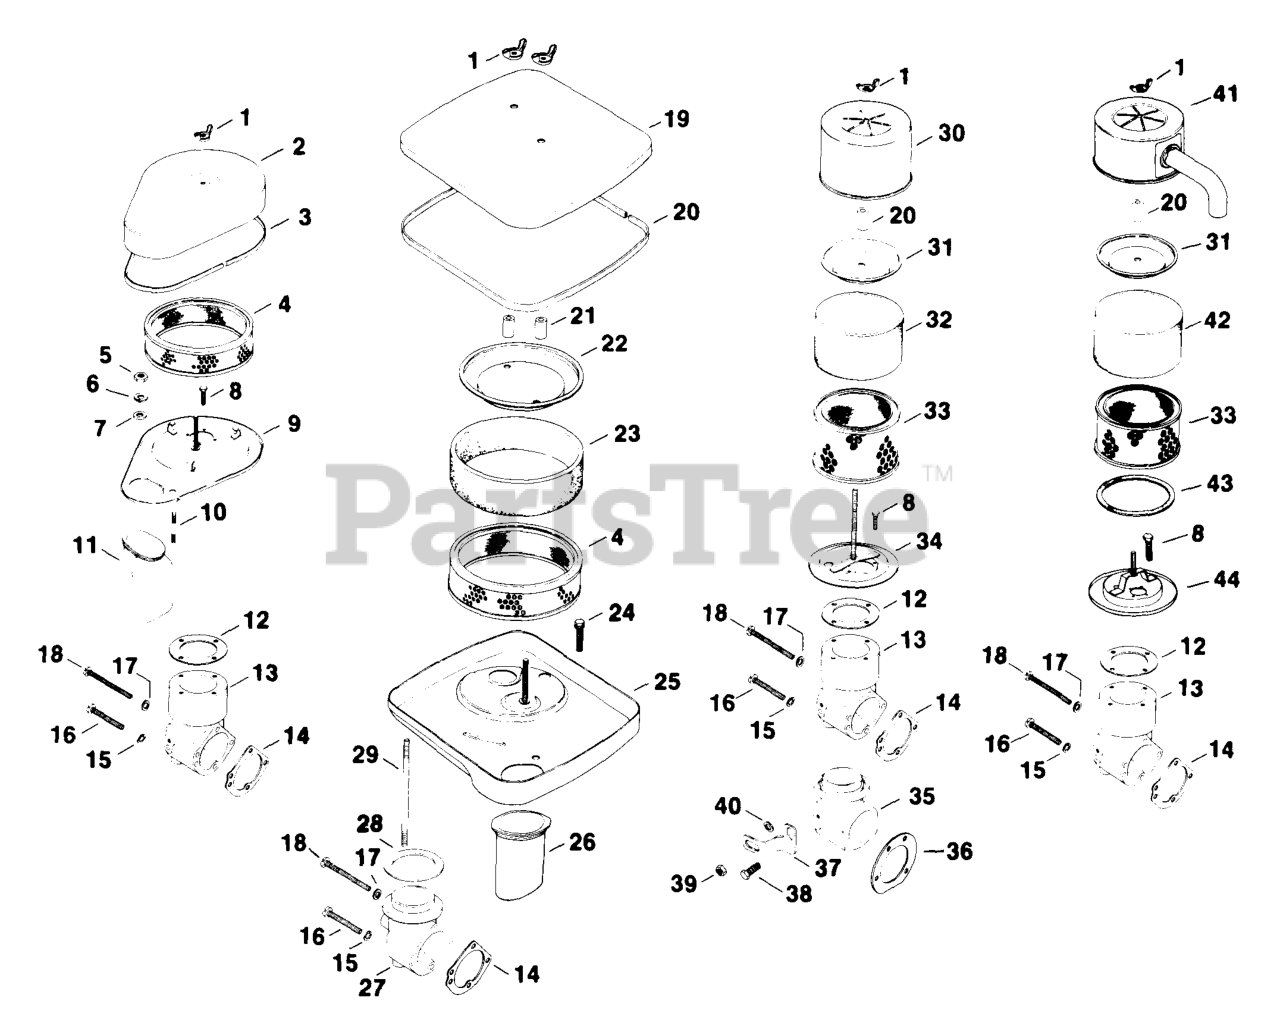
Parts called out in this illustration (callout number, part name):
1	NUT, WING 1/4-20 USE 25 100 15-S
14	GASKET - USE 25 041 06
15	WASHER, INT TOOTH LOCK #10
16	SCREW, SLT PAN HD 10-32X1 1/2" USE 25 086 63-S
17	WASHER, FLAT 3/16"
18	SCREW, SLT PAN HD 10-32X2 1/4"
19	COVER - (#DSC)
20	SEAL, AIR CLEANER - (#DSC)
24	SCREW, WSH HD TAP 1/4-20X7/16" USE 25 086 106-S
25	BASE - USE 52 201 07
27	ELBOW - USE 52 754 03
29	STUD,1/4-20x4-3/4" USE 25 072 10-S
